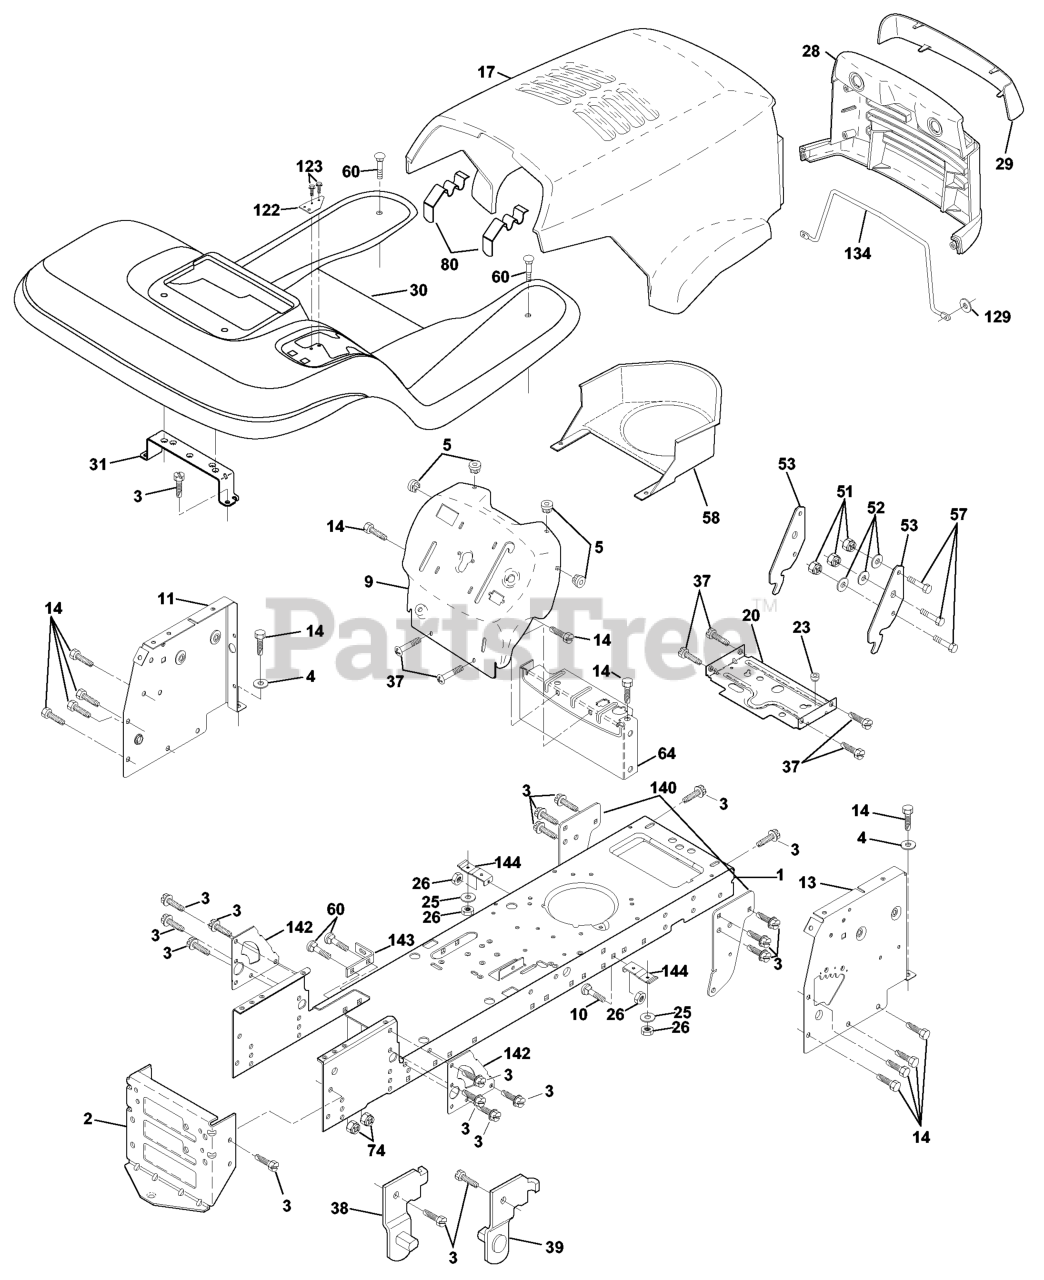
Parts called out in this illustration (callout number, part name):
1	CHASSIS WELDMENT
2	STRETCH DRAWBAR
3	SCREW
4	Washer 13/32 x 3/4 x 16 Ga.
5	BUMPER.RUBBER.HOOD
9	DASH P/L GREY LTH-120
10	BOLT D
11	PANEL DASH LH
13	PANEL DASH RH
14	SCREW LT
17	HOOD - LT/YT
20	PLATE MTG
23	BUSHING.SNAP.NYL.BLK.
25	WASHER
26	NUT
28	GRILLE LT/PL HUSQVARNA
29	LENS LT/PL HUSQVARNA
30	FENDER FOOTREST
31	BRACKET.SUPPORT.FENDER
37	Screw Thdrol 6/16-18 x 1/2 TYT
38	BRACKET LH PIVOT
39	BRACKET RH PIVOT
51	LOCKNUT.NYLOC.1/4-20
52	WASHER
53	BRACKET PNT PICK OFF LT/PL
57	BOLT
58	AIR DUCT P/L/LT
60	Bolt Rdhd Sqnk 3/8-16unc x 3/4
64	DASH LOWER
80	LATCH HOOD
129	WASHER
134	ROD SUPPORT HOOD LT/PL HUSQ
140	BRACKET CHASSIS FRONT
142	PLATE REINFORCEMENT
143	BRACKET, SWAY BAR
144	BRACKET FOOTREST
146	SCREW TORX HD 5/16X18
